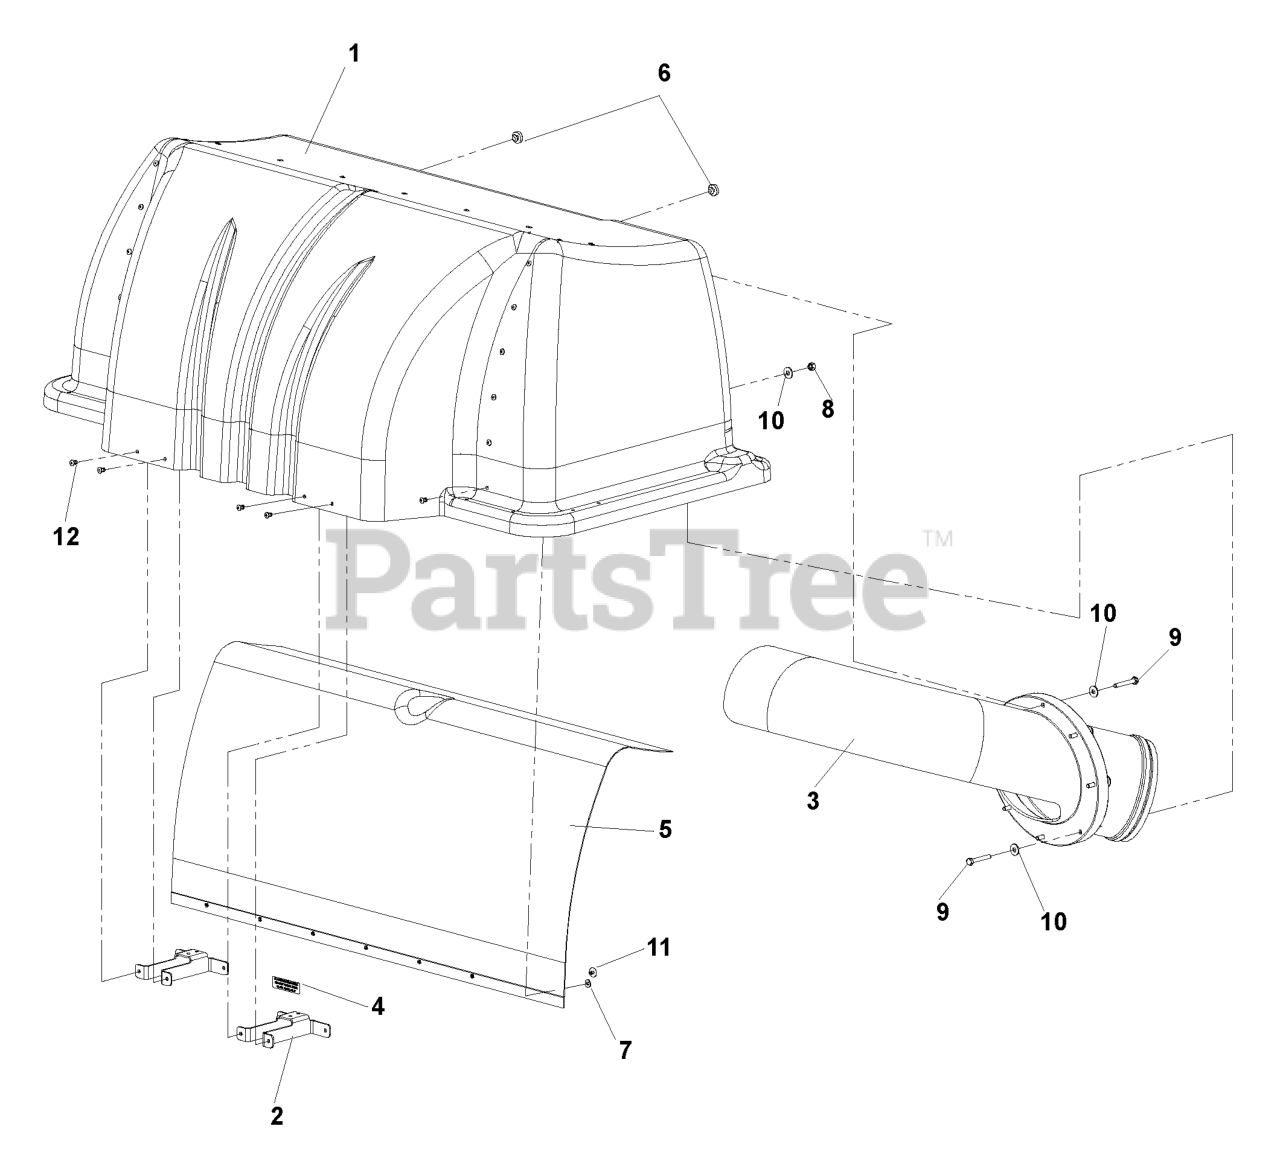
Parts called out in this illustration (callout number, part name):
2	SUPPORT, DRAW LATCH
4	DECAL, VENTILATION
5	MESH, POLY DIAMOND
6	GROMMET, BUMPER
7	WASHER #10
8	NUT.1/4-20.HEX.NYLOC.ZD
9	BOLT 1/4C X 1 3/4
10	WASHER 1/4 FLAT
11	RIVET E/16 X 1/4 LG FLG
12	RIVERT, 3/16, STAVEX
